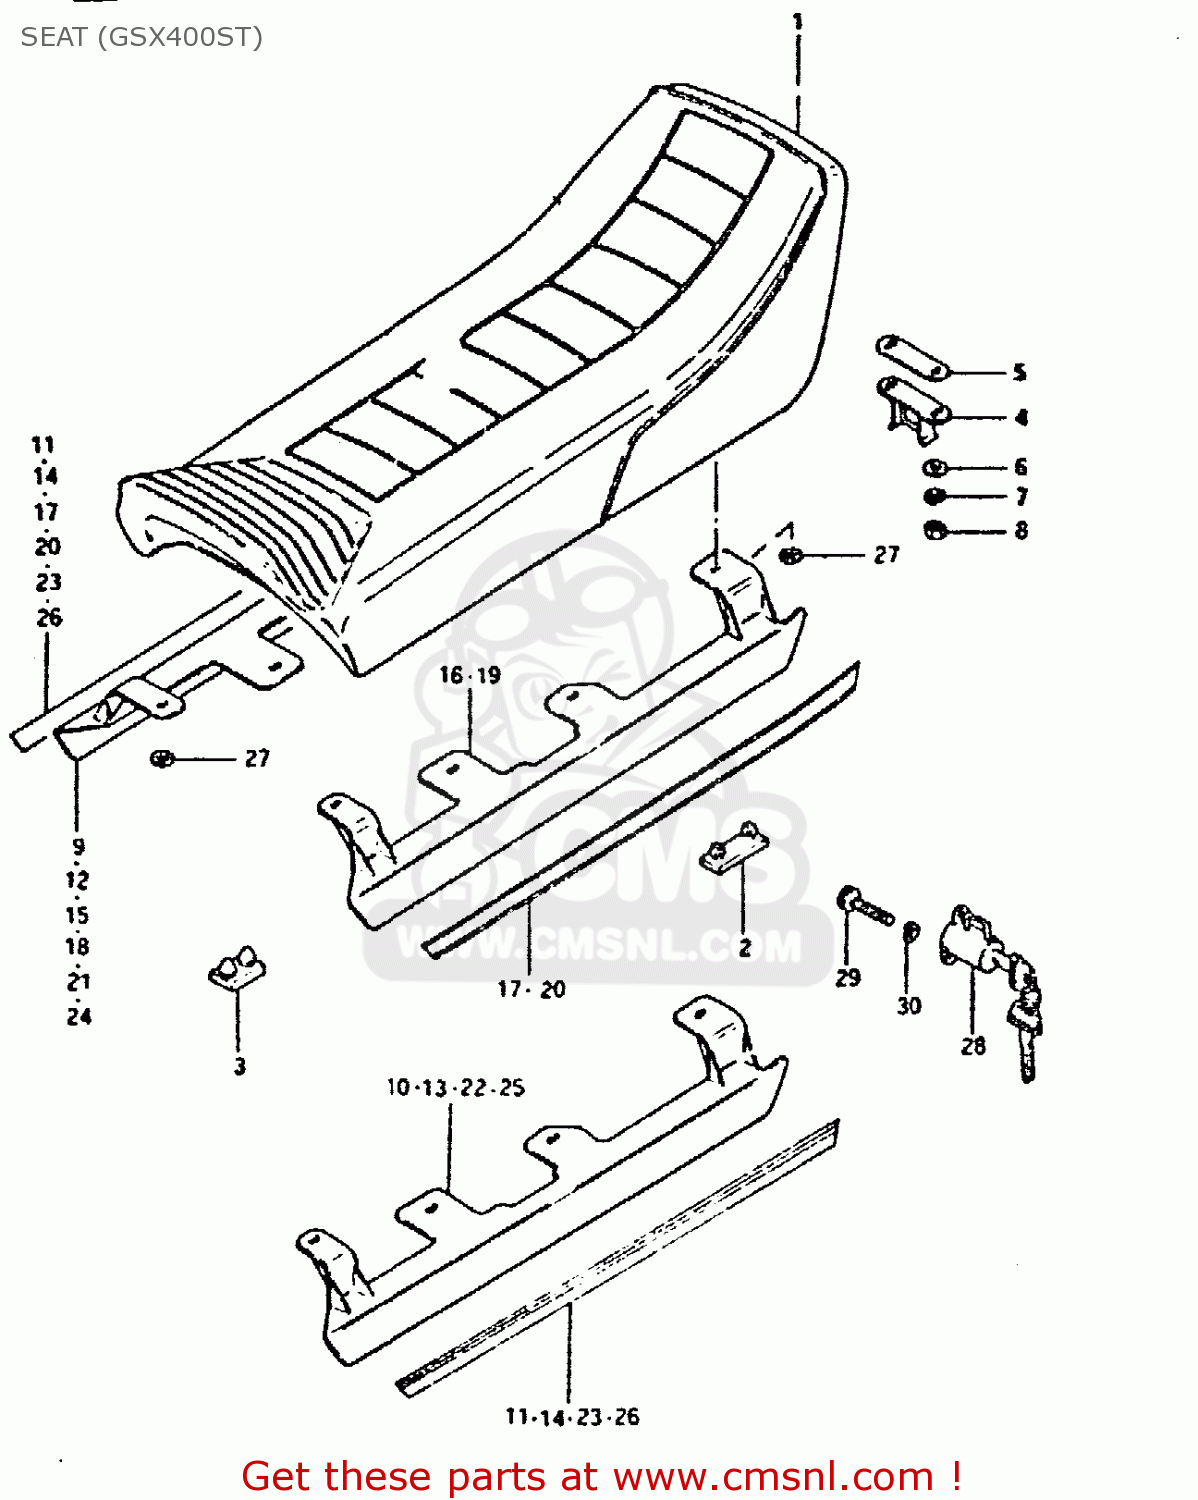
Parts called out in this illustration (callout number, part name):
1	SEAT ASSEMBLY
2	CUSHION
3	CUSHION
4	STRIKER,SEAT LOCK
5	SHIM,SEAT LOCK STRIKER
6	WASHER
7	LOCK WASHER
8	NUT 6MM
9	MOLDING,SEAT
10	MOLDING,SEAT
11	TAPE SET
12	MOLDING,SEAT
13	MOLDING,SEAT
14	TAPE SET
27	NUT
28	LOCK ASSEMBLY,HELMET
29	BOLT 6X11
30	LOCK WASHER
